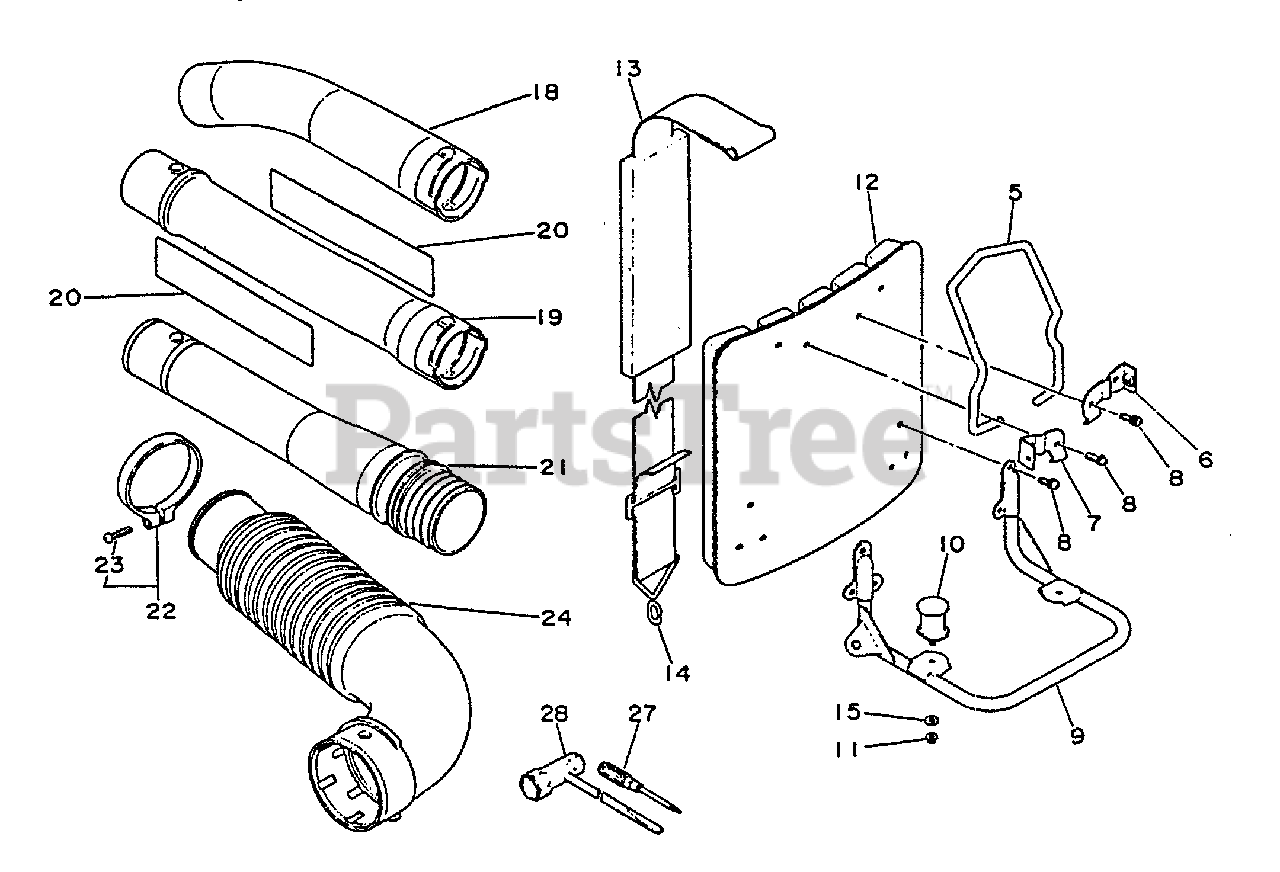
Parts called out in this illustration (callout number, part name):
7	BRACKET, HANGER
8	SCREW 5×10
9	STAND
11	NUT, FLANGE M6
12	CUSHION, BACKPACK
13	BACKPACK STRAP ASSY
14	RING, STRAP
15	WASHER 6.5×18×1.6
18	TUBE, BLOWER - CURVED
19	TUBE, BLOWER - STRAIGHT
20	LABEL - ECHO
21	TUBE, SWIVEL
22	CLAMP KIT
23	SCREW 5×20
24	TUBE, FLEXIBLE
27	SCREWDRIVER - CROSS HEAD
28	T-WRENCH 10×19 MM
